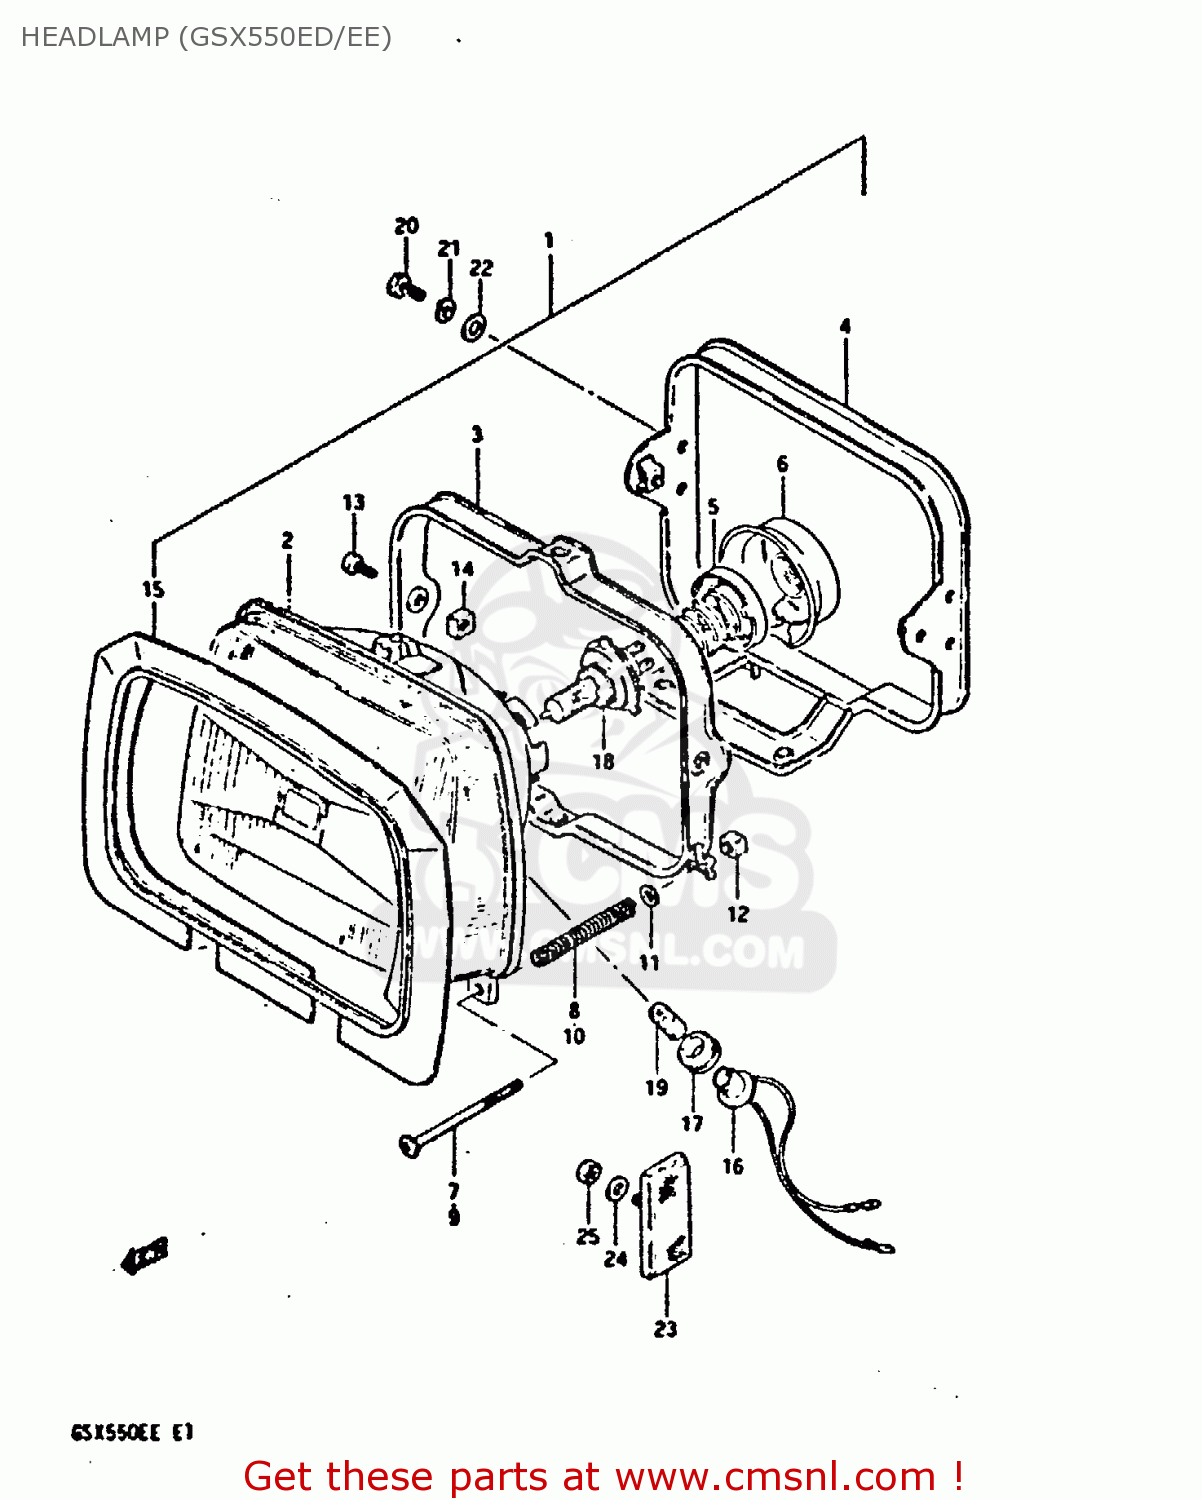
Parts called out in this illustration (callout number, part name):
1	HEADLAMP ASSY
2	UNIT
3	RING,MOUNTING
4	HOUSING
5	HOLDER
6	COVER,HEADLAMP SOCKET
7	SCREW,HEADLAMP ADJUST
8	SPRING
9	SCREW,HEADLAMP ADJUST
10	SPRING,HEADLAMP ADJUST
11	WASHER
12	NUT
13	SCREW
14	NUT
15	SHADE
16	SOCKET
17	JOINT,RUBBER
18	BULB(12V60/55W,H4)
19	BULB(12V4W)
20	BOLT
21	WASHER,LOCK
22	WASHER, LOWER
